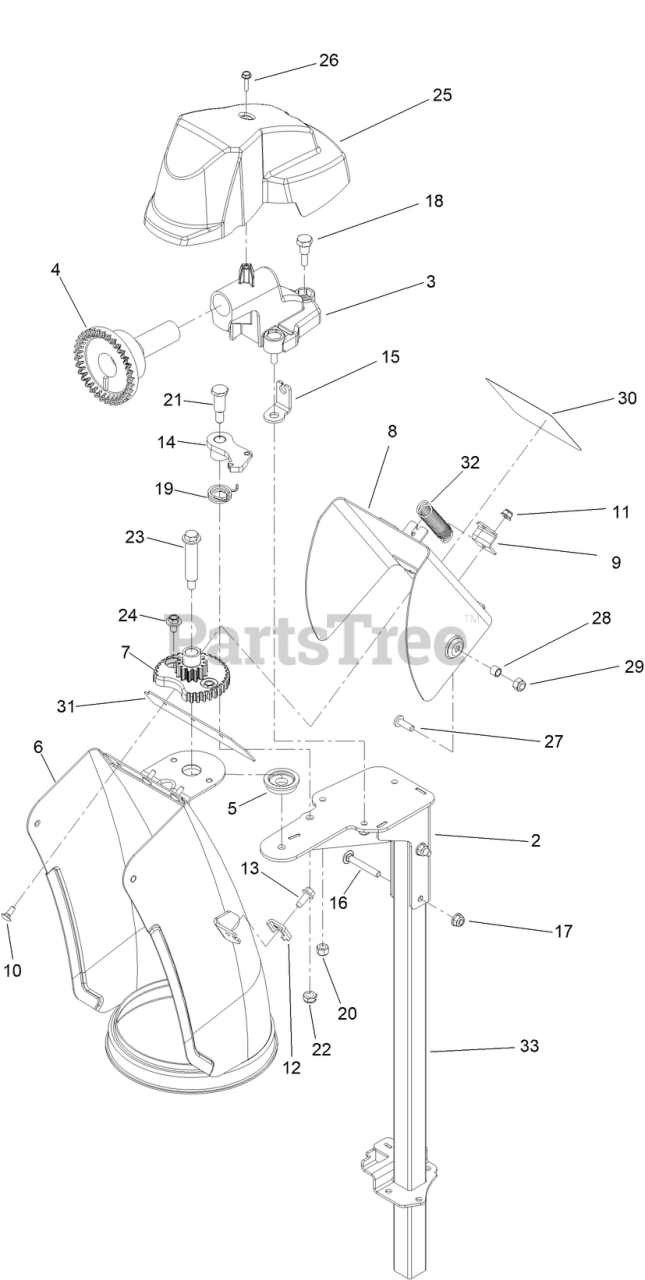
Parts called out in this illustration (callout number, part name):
2	SUPPORT-CHUTE WELD ASM, UPPER
3	MOUNT-GEAR, FACE
4	GEAR-FACE
5	SPACER-CHUTE
6	CHUTE WELD ASM
7	GEAR-CHUTE
8	DEFLECTOR WELD ASM
9	BRACKET-SPRING
10	BOLT-CARR
11	NUT-HF
12	CLAMP-CABLE
13	SCREW-HWH
14	LATCH-CHUTE
15	ANCHOR-CABLE
16	BOLT-CARR
17	NUT-FLANGE, NI
18	SCREW-SHOULDER
19	SPRING-TORSION
20	NUT-HEX
21	SCREW-SHOULDER, HH
22	NUT-HEX
23	BOLT-SHOULDER
24	SCREW-HWH
25	COVER-CHUTE, GEAR
26	SCREW-HWH
27	SCREW-PH
28	SPACER
29	NUT-HEX
30	DECAL-DANGER
31	GASKET-DEFLECTOR
32	SPRING-CHUTE, UPPER
33	CHUTE SUPPORT ASM [BLACK]
